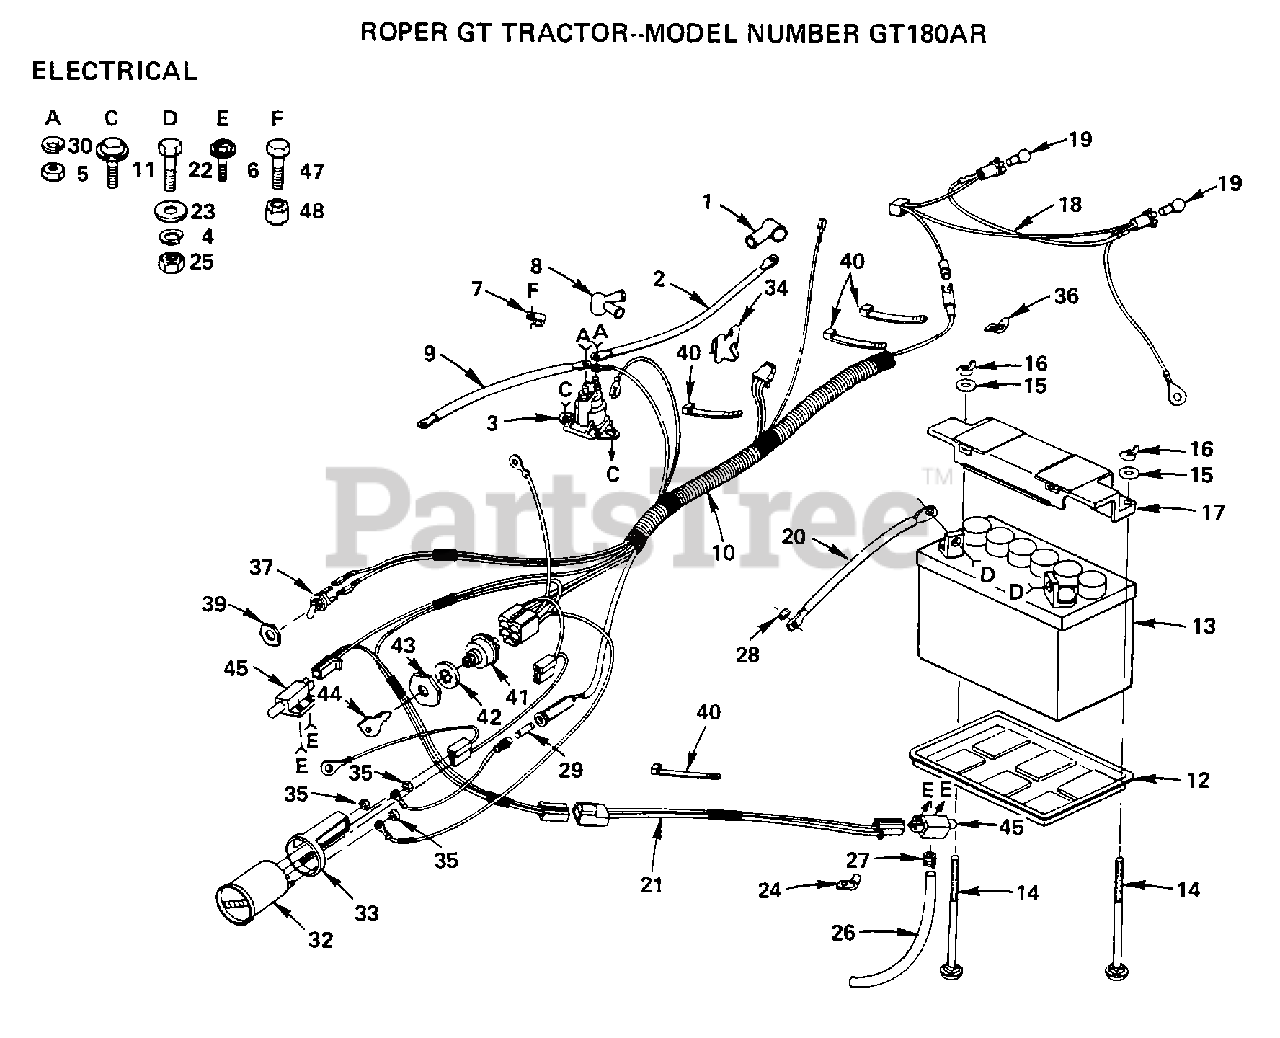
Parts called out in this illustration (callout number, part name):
4	LOCKWASHER
5	NUT
8	TERM COVER DUAL
9	CABLE-BATTERY T
11	SCREW
12	"TRAY T, BATTERY"
14	BOLT
15	WASHER PM
18	HARNESS T
19	HEADLAMP BULB
20	CABLE T
22	BOLT LT
23	WASHER
24	CLIP GTV
28	LOCKWASHER
29	FUSE-30 AMP
32	METER - HOUR, AMPS
33	BRACKET, AMMETER
34	CLIP-HARNESS
35	"NUT,KEPS"
36	CLIP GT
37	LIGHT SWITCH T
40	WIRE TIE
42	LOCKWASHER
43	CONDUIT NUT L
45	SWITCH-INTER. GT
47	BOLT
